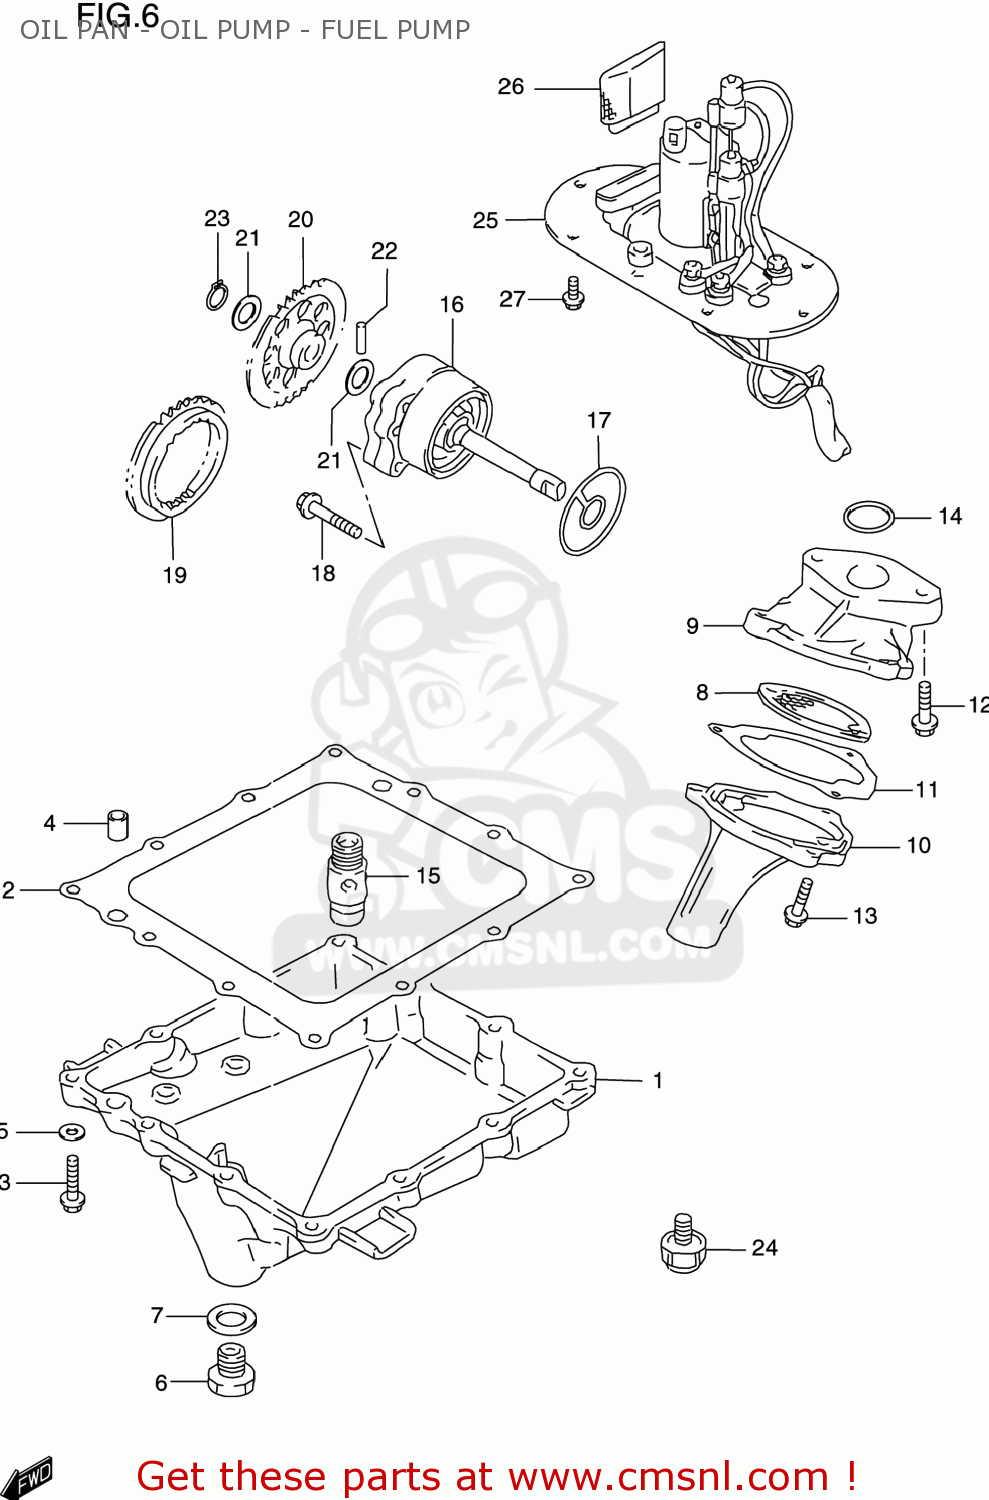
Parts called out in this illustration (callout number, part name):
1	PAN,OIL
2	GASKET,OIL PAN (NAS)
3	BOLT,G/S SWITC
4	PIN
5	GASKET(5.8X11X1.2) (NAS)
6	PLUG
7	GASKET(13.8X18.8X4.8) (NAS)
8	STRAINER,ENGINE OIL
9	PROTECTOR,OIL STRAINER
10	COVER,OIL STRAINER
11	GASKET,OIL STRAINER
12	BOLT
13	BOLT
14	O RING(D:2.62,ID:20.3)
15	VALVE ASSY,OIL RELIEF
16	PUMP ASSY,ENGINE OIL
17	O RING,OIL PUMP
18	BOLT
19	GEAR,OIL PUMP DRIVE
20	GEAR,OIL PUMP DRIVEN
21	SHIM
22	PIN(5X18)
23	CIRCLIP,12 MM
24	SWITCH ASSEMBLY,OIL PRESSURE
25	PUMP ASSY,FUEL
26	STRAINER,FUEL PUMP
27	BOLT
